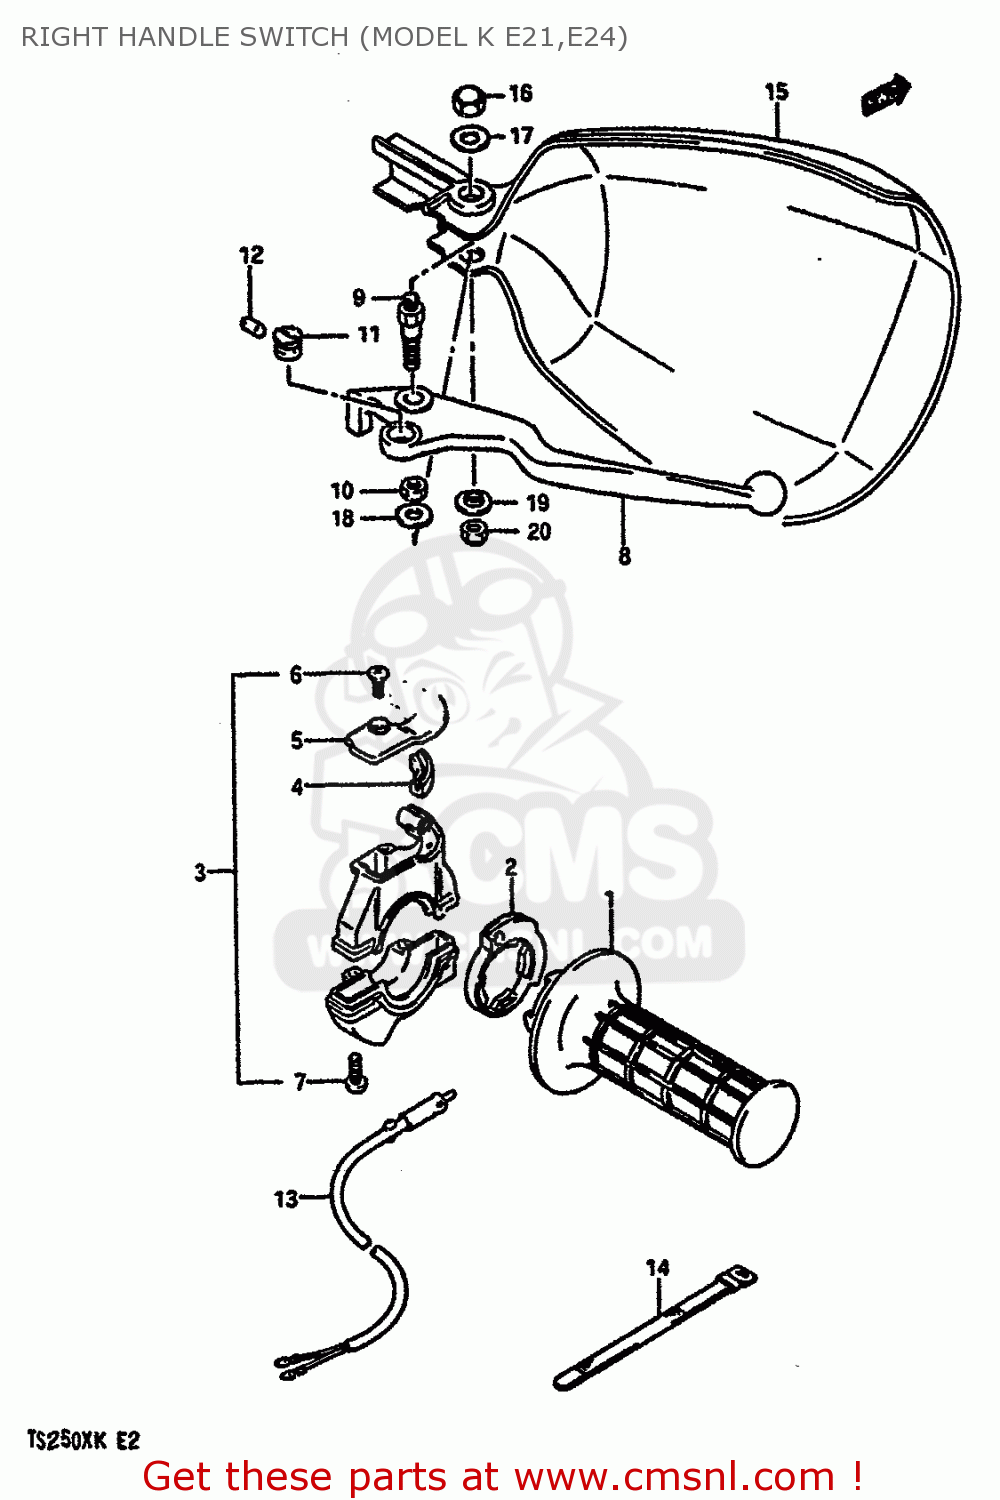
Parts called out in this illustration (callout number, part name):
1	GRIP,THROTTLE
2	ROTOR,THROTTLE GRIP
3	CASE ASSY,THROTTLE
4	GUIDE PIECE,THROTTLE
5	COVER,THROTTLE CASE
6	SCREW
7	SCREW
8	LEVER,BRAKE
9	BOLT,BRAKE LEVER PIVOT
10	NUT
11	ADJUSTER
12	ROD,PUSH
13	SWITCH ASSY,STOP
14	CLAMP(L:120)
15	COVER,KNUCKLE RH (WHITE)
16	NUT 6MM
17	WASHER (6.5X20X1.6)
18	WASHER
19	WASHER
20	NUT
